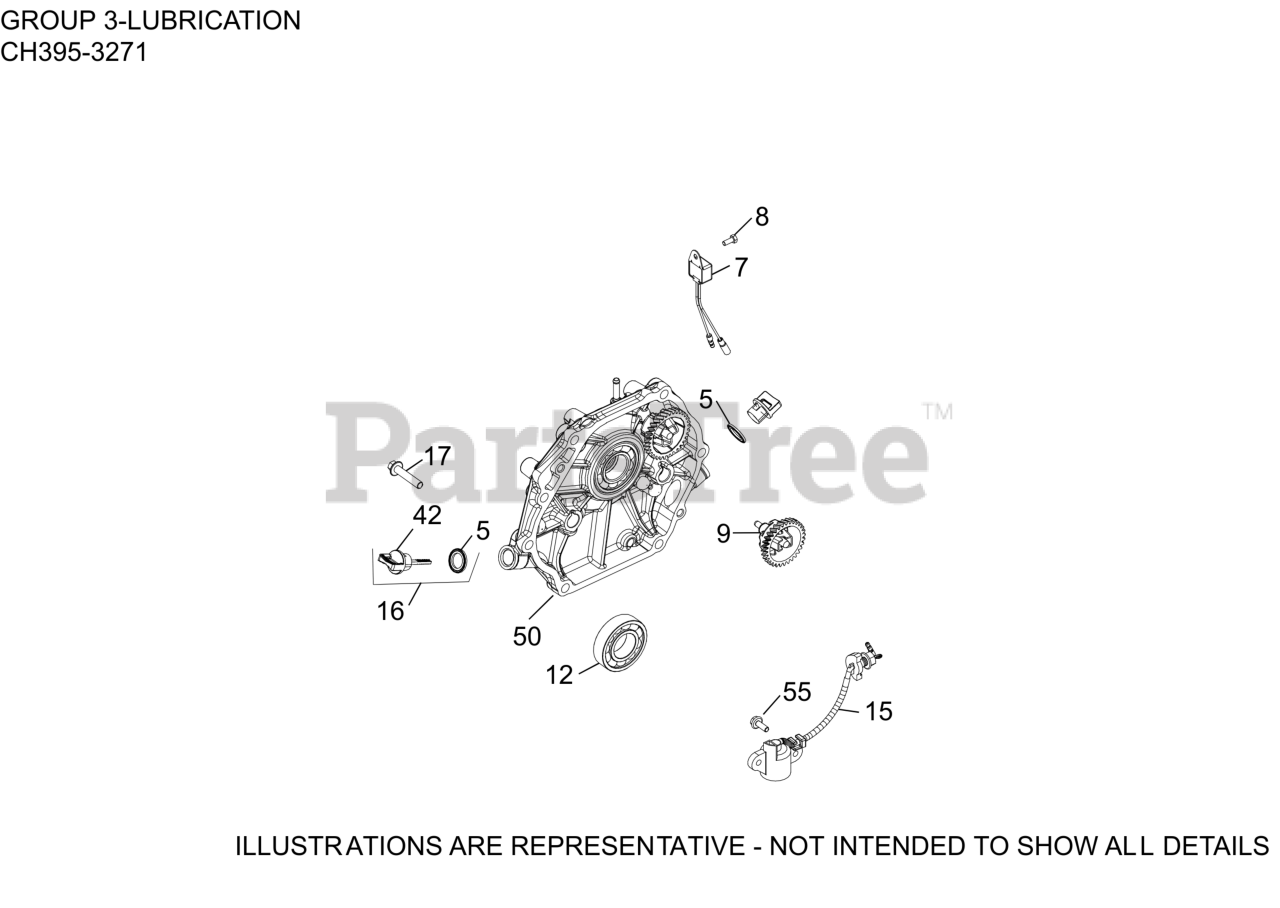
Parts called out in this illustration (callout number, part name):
5	SEAL, DIPSTICK
7	CONTROL, OIL ALERT UNIT
8	SCREW, HEX/PHILLIPS M5
9	GOVERNOR, ASSEMBLY
12	BEARING, CRANKSHAFT
15	SWITCH, OIL SENSOR ASSEMBLY
16	DIPSTICK ASSEMBLY
17	SCREW, CLOSURE PLATE
42	DIPSTICK - USE 17 038 08-S
50	PLATE, CLOSURE & BEARING
55	SCREW, M6 X 16
